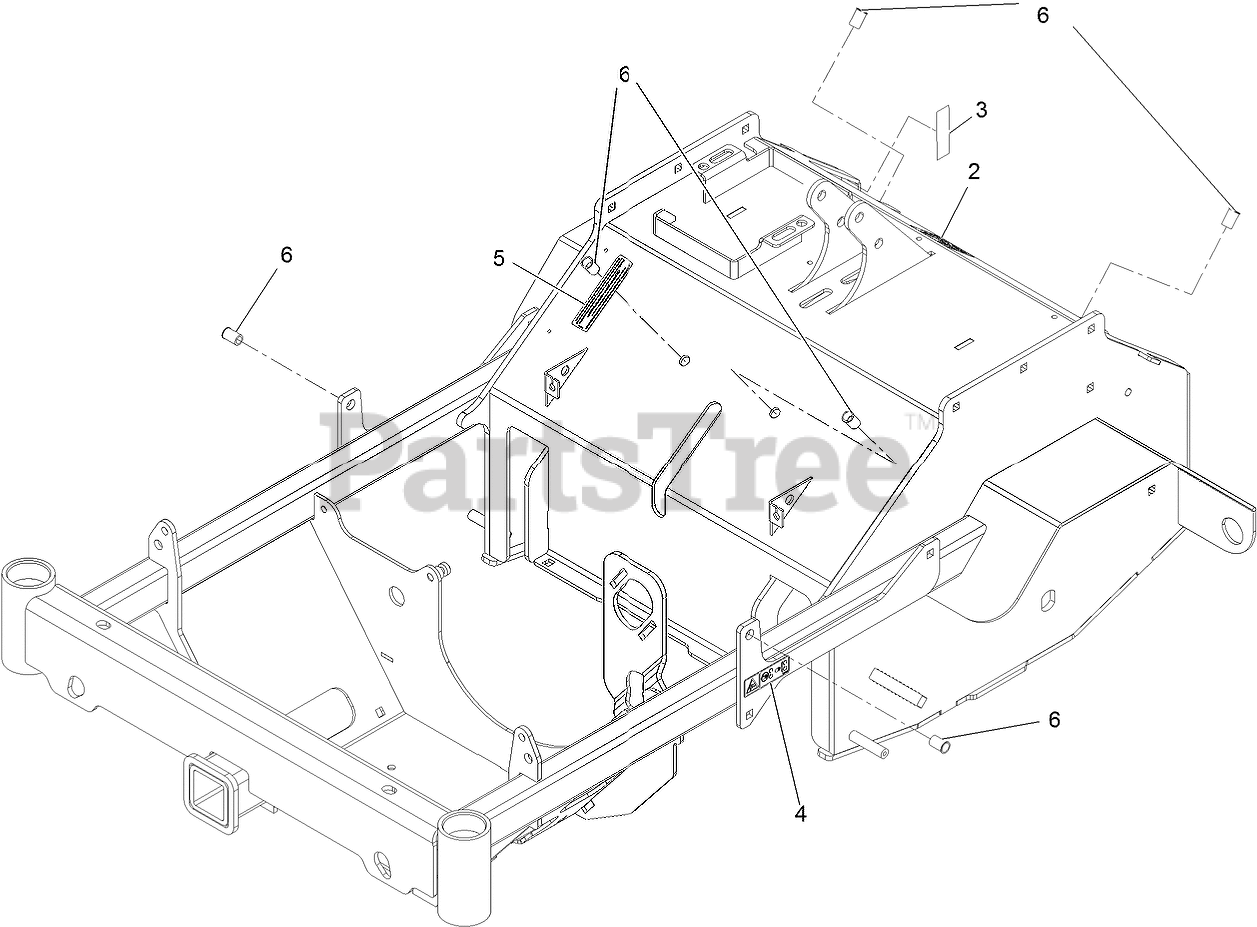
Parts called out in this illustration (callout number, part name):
2	DECAL-WARNING
3	DECAL-WARNING
4	DECAL-DANGER
5	DECAL-ARRESTOR, SPARK
6	NUT-CLINCH
